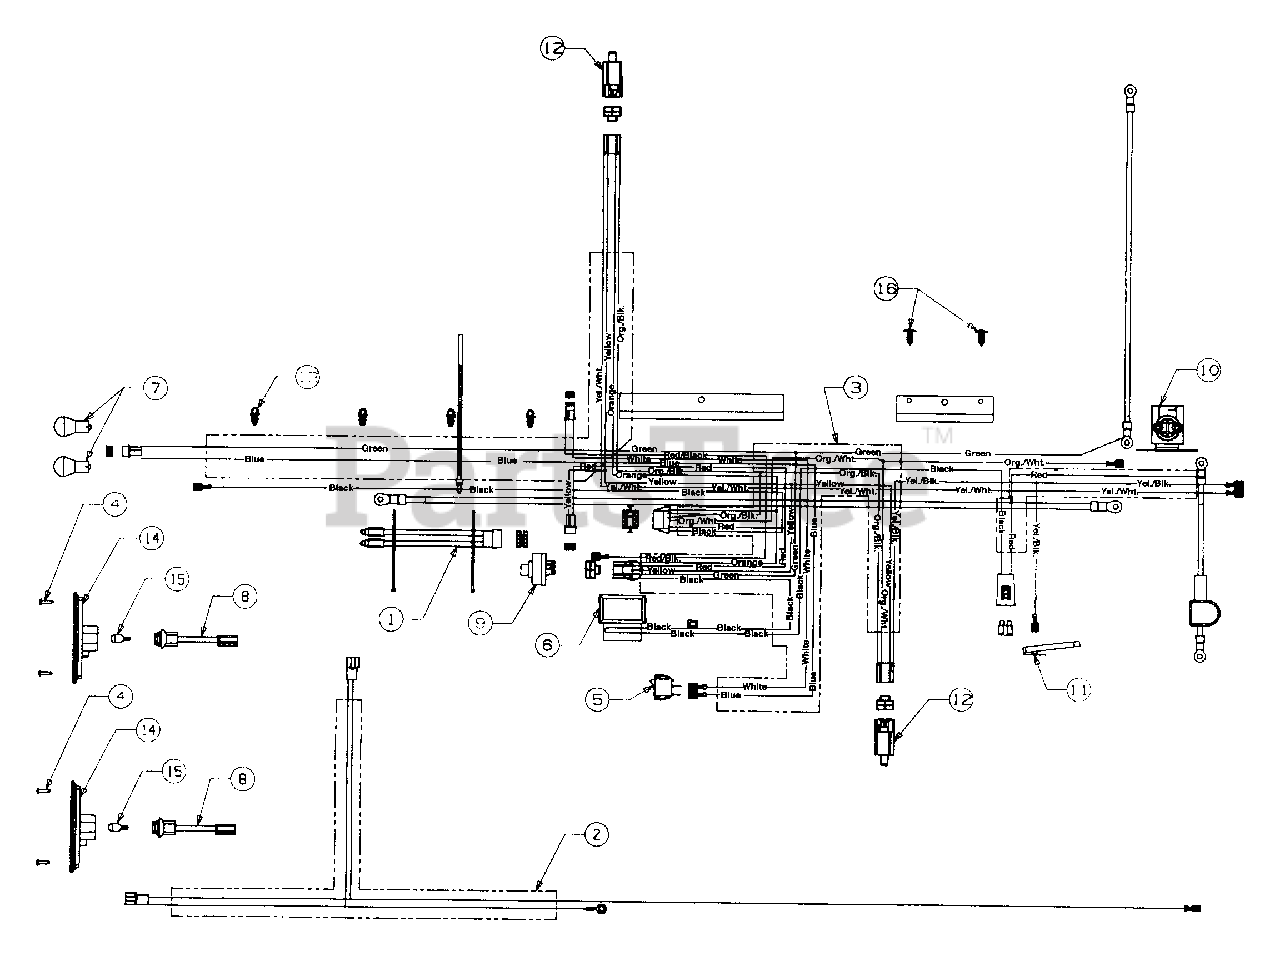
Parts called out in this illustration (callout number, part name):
1	Harness Adapter (Monitor)
2	Harness Adapter (Tail light)
3	Wire Harness
4	Truss Machine Screw
5	Light Switch
6	Ammeter
7	Bulb (Headlight)
8	Wire Harness (Tail light)
9	Ignition Switch
10	Solenoid
11	Safety Switch (Reverse)
12	Safety Switch
14	Tail light
15	Bulb (Tail light)
